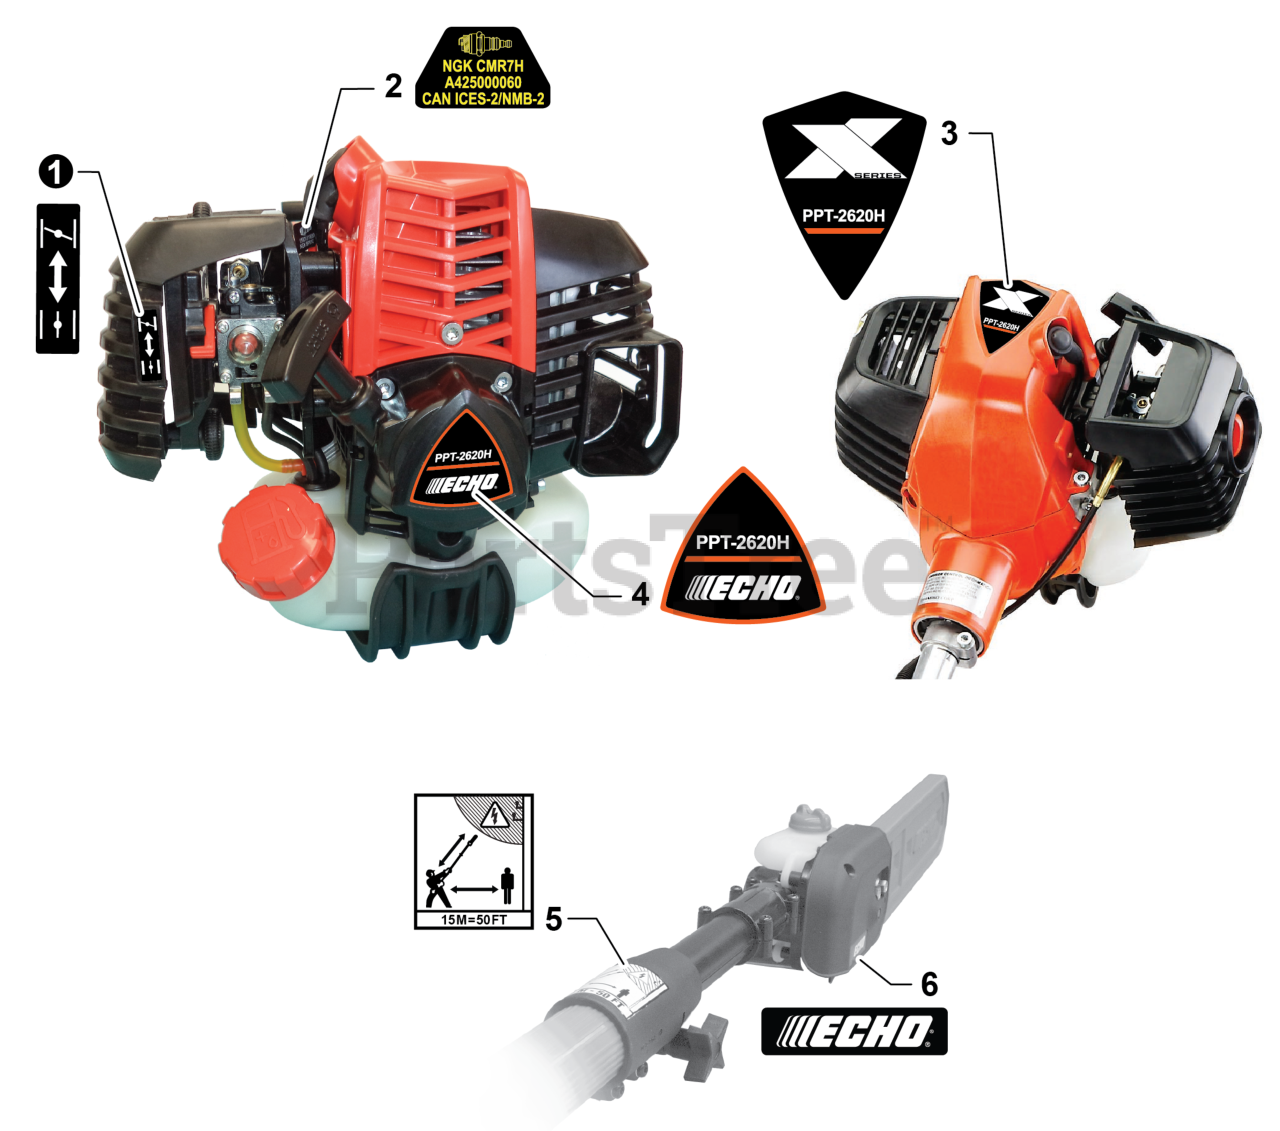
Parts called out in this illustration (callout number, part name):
1	LABEL - CHOKE
2	LABEL - SPARK PLUG - CMR7H
3	LABEL - MODEL PPT-2620H
4	LABEL - RECOIL STARTER - PPT-2620H
5	LABEL - CAUTION
6	LABEL - ECHO
